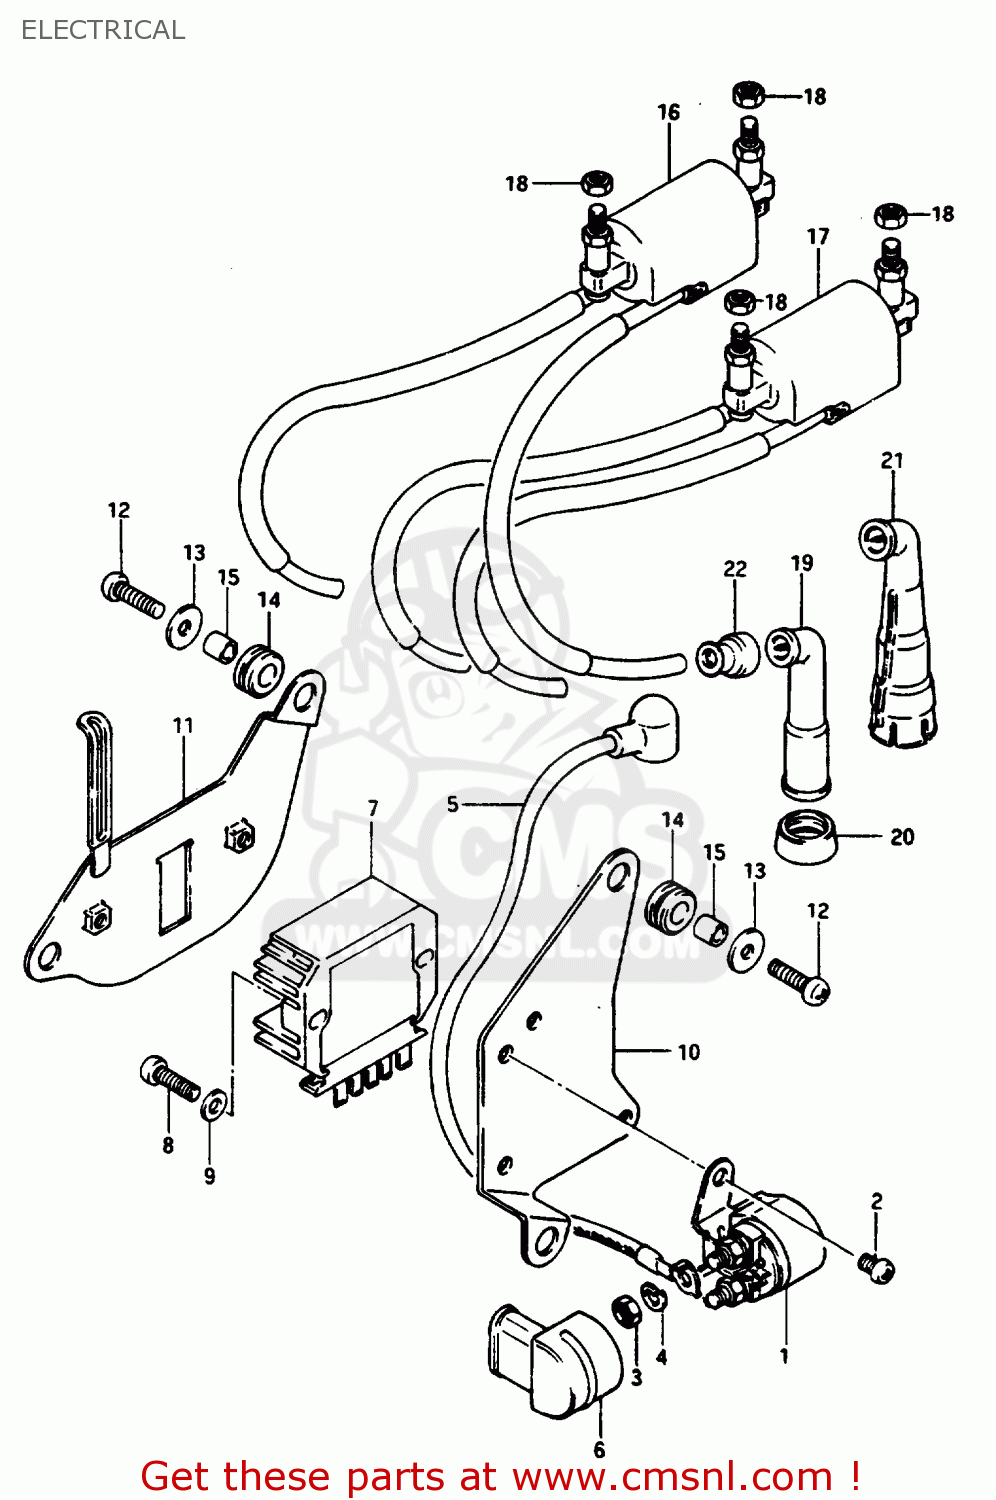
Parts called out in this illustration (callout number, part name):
1	RELAY ASSY,STARTING MOTOR
2	SCREW
3	NUT
4	WASHER,LOCK
5	WIRE,STARTER MOTOR LEAD
6	CAP,STARTER RELAY TERMINAL
7	RECTIFIER ASSEMBLY
8	SCREW
9	WASHER, LOWER
10	HOLDER COMP,ELECTRONIC PARTS
11	PLATE,ELECTRIC PARTS H
12	SCREW
13	WASHER
14	CUSHION
15	SPACER (6.3X9.1X6.7)
16	COIL ASSEMBLY,IGNITION
17	COIL ASSEMBLY,IGNITION NO
18	NUT
19	CAP,SPARK PLUG
20	SEAL,SPARK PLUG CAP
21	CAP, SPARK PLUG
22	SEAL,SPARK PLU
